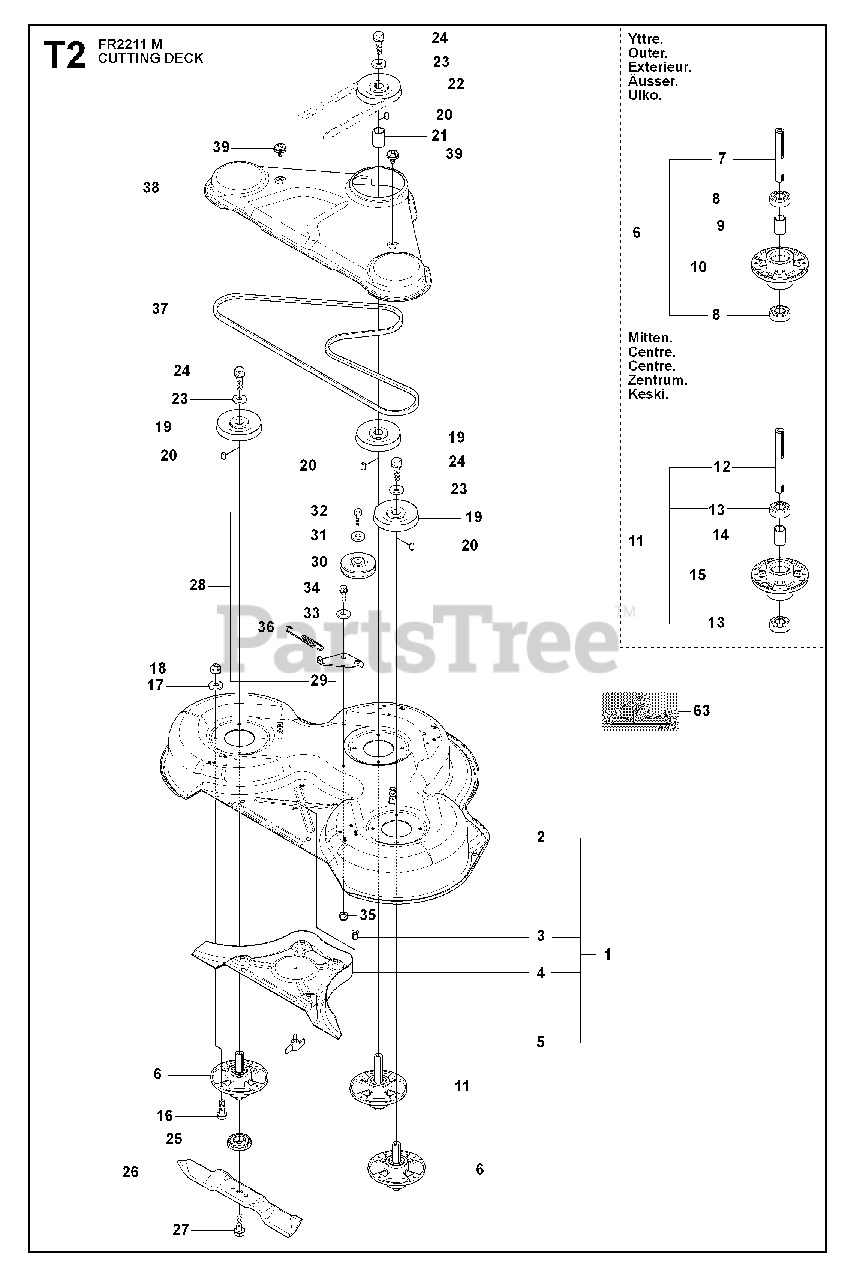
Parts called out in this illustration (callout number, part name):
6	RP SPINDLE ASSY
10	BEARING HOUSING
15	BEARING HOUSING
17	WASHER BRB 8.4X17
18	LOCKNUT M8
30	PULLEY
33	WASHER
35	LOCKNUT M8
